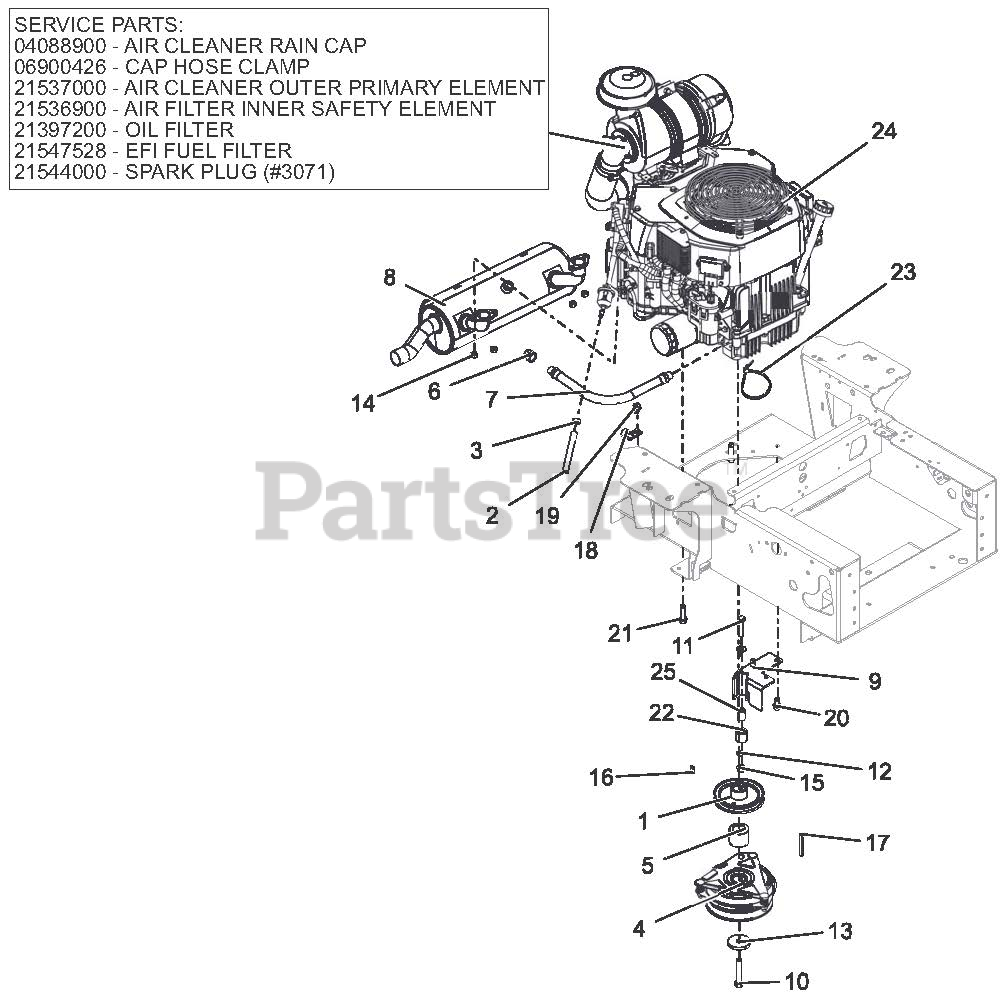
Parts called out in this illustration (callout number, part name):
1	PULLEY, 4.50 OD X 1.127 ENGINE - BLACK
2	.25 LOW-PERM GAS HOSE 6.00" LG - VALVE TO ENGINE
3	CLAMP, FUEL LINE
4	CLUTCH, OGURA GT2.5-FE02
5	SPCR, 1.125 X 1.75 X 1.400
6	PIPE, CAP 3/8 NPT FEMALE
7	HOSE, HYD .38-11-OK M6N0-M6N0
8	MUFFLER, KOHLER EFI
9	BRKT, CLUTCH STOP
10	BLT-HEX 0.44-20 X 2.50 GR5 EP80 YWZC
11	BLT-HEX .38-16 X 1.75 GR5 YWZC
12	WSHR-FL-STL .406 X .812 X .065 YWZ
13	WSHR-FL-STL .469 X 2.00 X .25 YWZC
14	NUT-LK-TOP M8-1.25 YWZC
15	NUT, LK-TOP-FLG .38-16 YWZC
16	KEY-SQ .250 X .250 X .625
17	KEY, .25 X .25 X 2.25
19	SCR-TAP .38-16 X .50 HWH TR YWZ
20	SCR-TAP .38-16 X .75 HWH TR YWZ
21	SCR-TAP .38-16 X 1.50 HWH TR YZ
22	BUMPER, RUBBER .62 X 1.0 X .88 LG
23	CABLE, TIE 5.50 LG
24	ENGINE, KOHLER EFI ECV740
24	AIR CLEANER RAIN CAP
24	CAP HOSE CLAMP
24	AIR CLEANER OUTER PRIMARY ELEMENT
24	AIR FILTER INNER SAFETY ELEMENT
24	OIL FILTER
24	EFI FUEL FILTER
24	SPARK PLUG - #3071
25	BUSH., S .391 X .622 X .95 ST REV A
